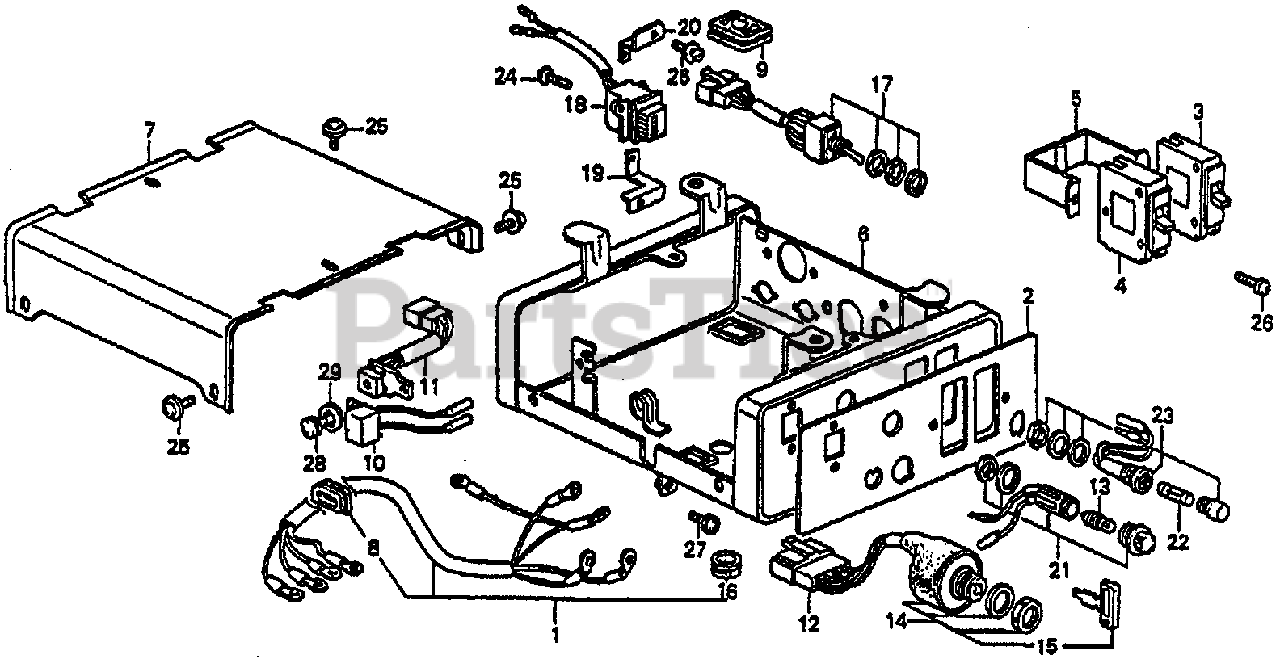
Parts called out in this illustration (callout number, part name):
1	WIRE, A.C. OUTLET
2	PANEL, BOX
3	BREAKER, CIRCUIT (33A) (NOT AVAILABLE)
4	BREAKER, CIRCUIT (16.5A) (NOT AVAILABLE)
5	SUPPORT, BREAKER (NOT AVAILABLE)
6	BOX, CONTROL *R8* (BRIGHT RED)
7	COVER, BOX (UPPER) *R8* (BRIGHT RED)
8	GROMMET, A.C. WIRE
9	GROMMET, REMOTE CONTROL
10	RECTIFIER ASSY., SILICON (STANLEY)
10	RECTIFIER, SILICON (NOT AVAILABLE)
11	STACK ASSY., DIODE
12	CONNECTOR, MALE (8 POLE)
13	BULB, DASH (24V-2W)
14	SWITCH ASSY., COMBINATION
15	KEY
16	GROMMET B, TUBE
17	SWITCH ASSY., CONTROL
18	METER, FREQUENCY
19	HOLDER A, FREQUENCY METER
20	HOLDER B, FREQUENCY METER
21	SOCKET ASSY., PILOT LAMP
22	FUSE (15A)
23	HOLDER, FUSE (NOT AVAILABLE)
24	SCREW, PAN (3X8)
25	SCREW-WASHER (5X12)
26	SCREW-WASHER (4X12)
27	SCREW-WASHER (5X10)
28	SCREW-WASHER (6X12)
29	WASHER, PLAIN (6MM)
